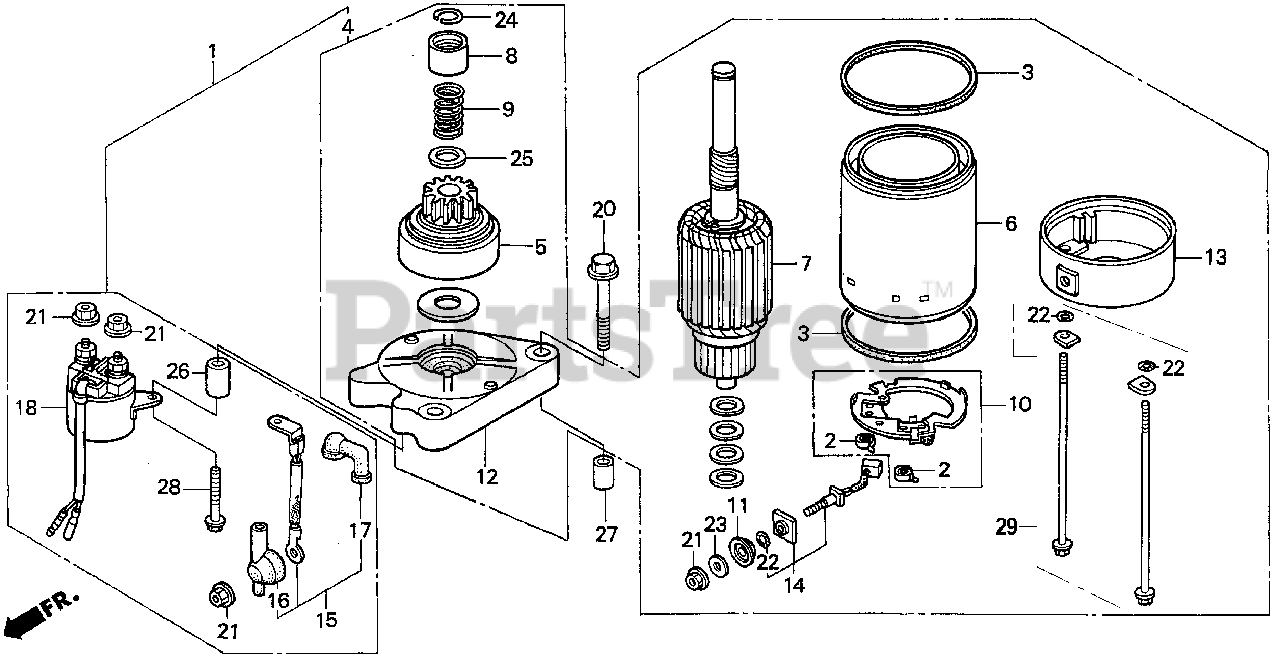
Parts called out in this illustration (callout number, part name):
1	MOTOR ASSY., STARTER
2	SPRING, CARBON BRUSH
4	MOTOR UNIT, STARTER
8	PIECE, STOPPER
9	SPRING, RETURN
10	HOLDER, BRUSH
12	BRACKET, FR.
13	BRACKET, RR.
14	UNIT, TERMINAL
15	WIRE, MAGNETIC SWITCH
16	COVER, STARTER TERMINAL
17	COVER, MAGNETIC SWITCH TERMINAL
18	SWITCH ASSY., STARTER MAGNETIC
20	BOLT, FLANGE (8X45)
21	NUT-WASHER (6MM)
23	WASHER (6MM)
24	CIRCLIP (14MM)
26	COLLAR, DISTANCE
27	PIN A, DOWEL (10X16)
28	BOLT, FLANGE (6X32)
29	BOLT SET, SETTING
